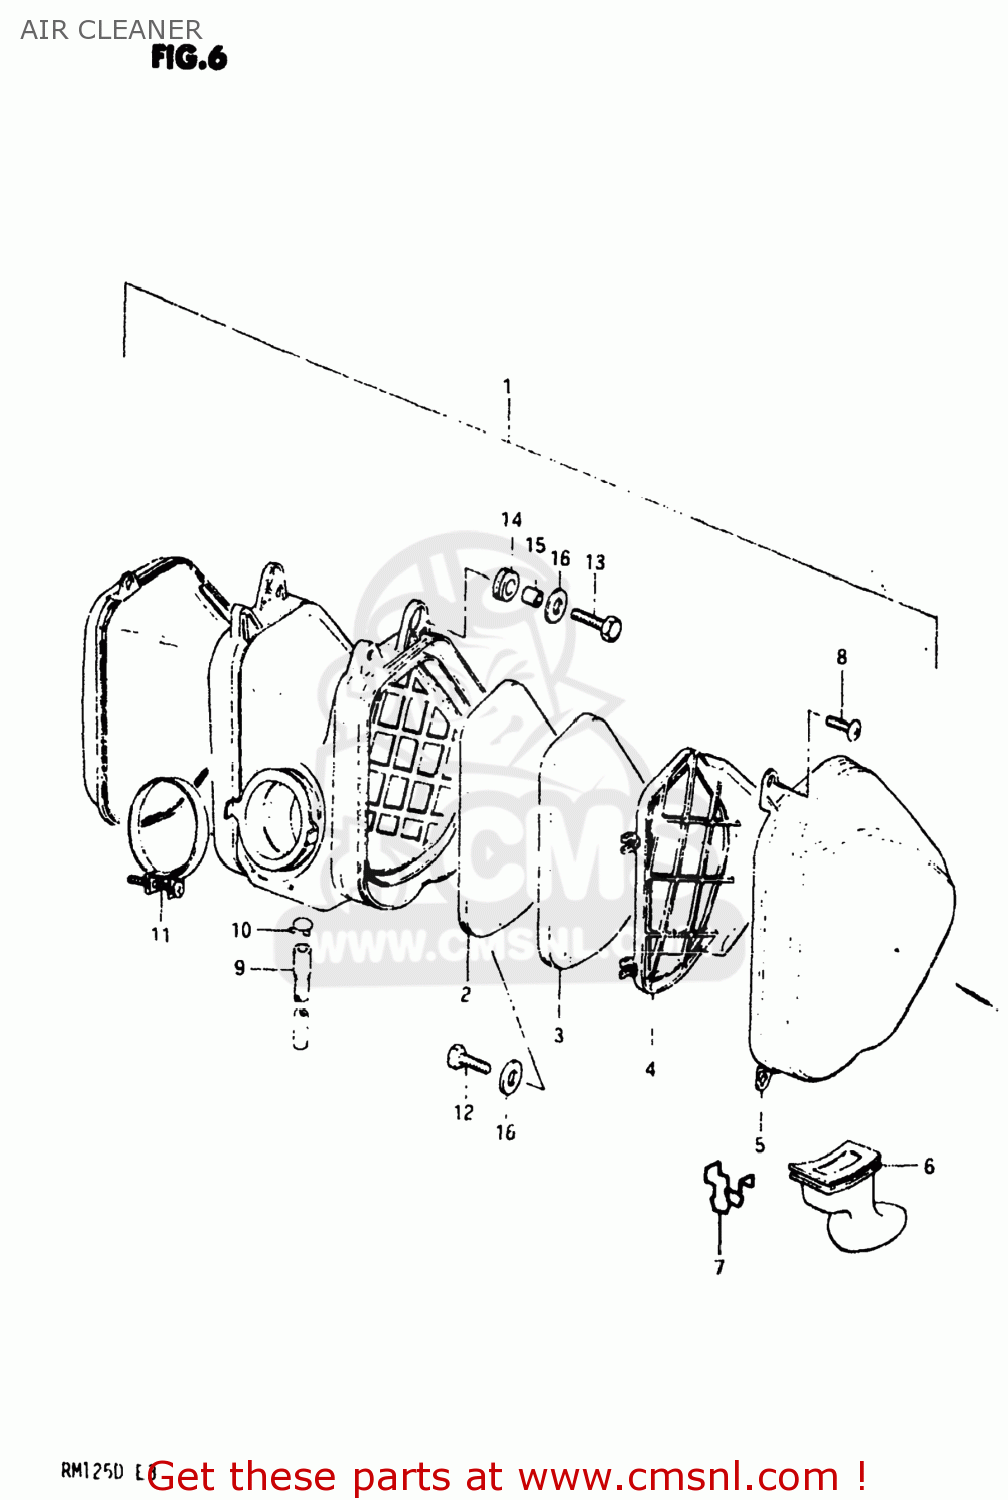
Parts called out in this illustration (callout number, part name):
1	CLEANER ASSEMBLY,AIR
2	FILTER,L
3	FILTER,2ND,R
4	HOLDER,AIR CLEANER ELEMENT
5	CAP,AIR CLEANER,LEFT
6	DRAIN TUBE,LEFT
7	DRAIN STOPPER
8	SCREW
9	DRAIN TUBE
10	CLIP
11	CLAMP
12	BOLT, UPPER
13	BOLT
14	CUSHION
15	SPACER (7X9X7)
16	WASHER
